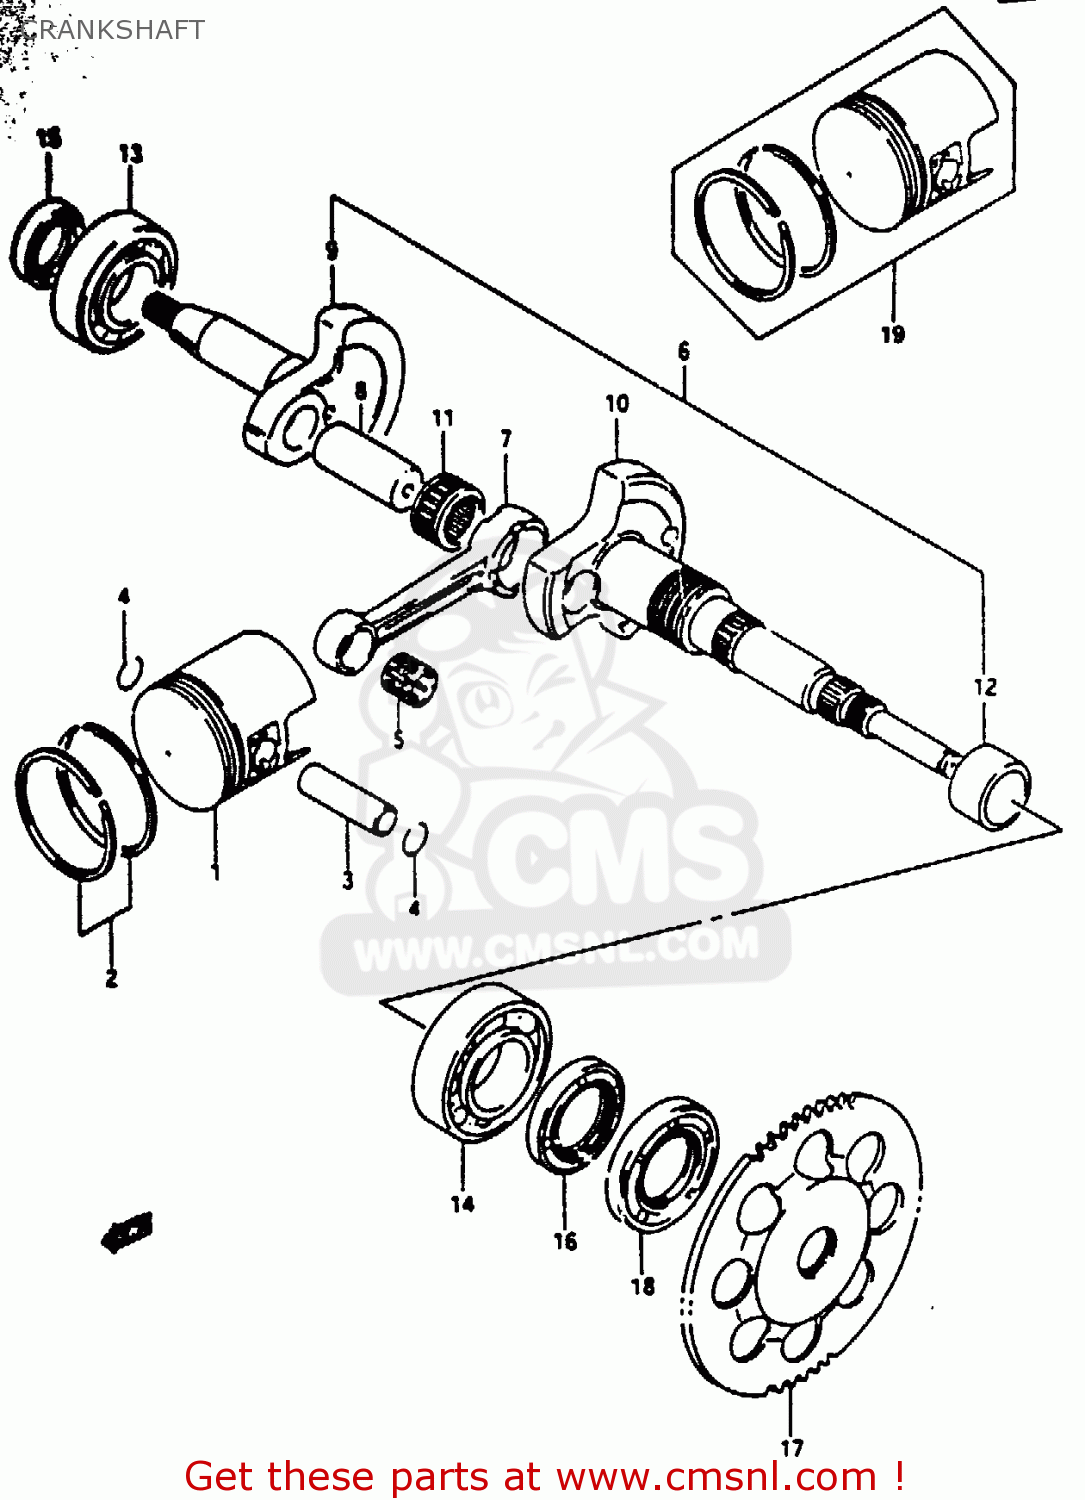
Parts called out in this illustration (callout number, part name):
1	PISTON (41.00MM)
2	RING SET,PISTON
3	PIN,PISTON
4	CIRCLIP
5	BEARING 10X14X12.5
6	CRANKSHAFT ASSEMBLY
7	CONNECTING ROD
8	PIN,CRANK
9	CRANKSHAFT,R
10	CRANKSHAFT,L
11	BEARING
12	SPACER(18X24X14)
13	BEARING 20X47X14
14	BEARING(25X52X13)
15	SEAL,OIL (17X27X6)
16	SEAL,OIL(25X37X6)
17	GEAR,STARTER
18	SEAL,OIL(24X43X6)
19	PISTON SET (OS:05)
